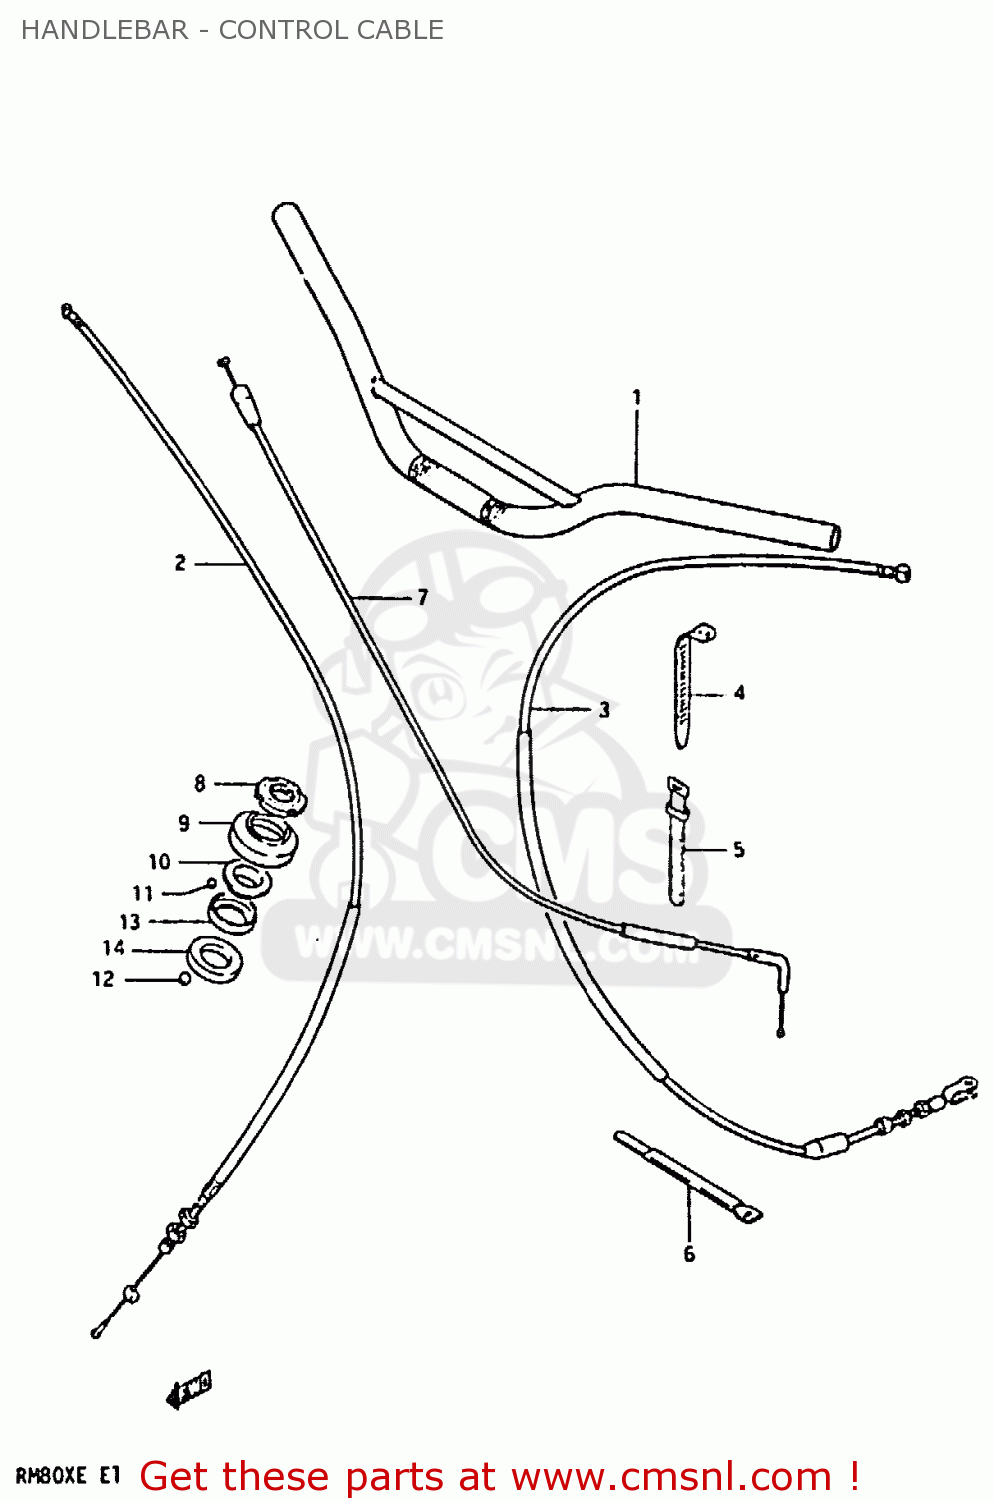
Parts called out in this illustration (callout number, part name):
1	HANDLEBAR
2	CABLE,FR BRAKE
3	CABLE ASSY,CLUTCH
4	CLAMP(L:125)
5	CLAMP
6	CLAMP
7	CABLE ASSEMBLY,THROTTLE
8	NUT,STEERING STEM(25X44X10)
9	DUST SEAL,STEERING UPR
10	RACE,STEERING OUTER UPR
11	BALL
12	BALL
13	RACE,STEERING INNER UPR
14	LACE,STEERING INNER LWR
